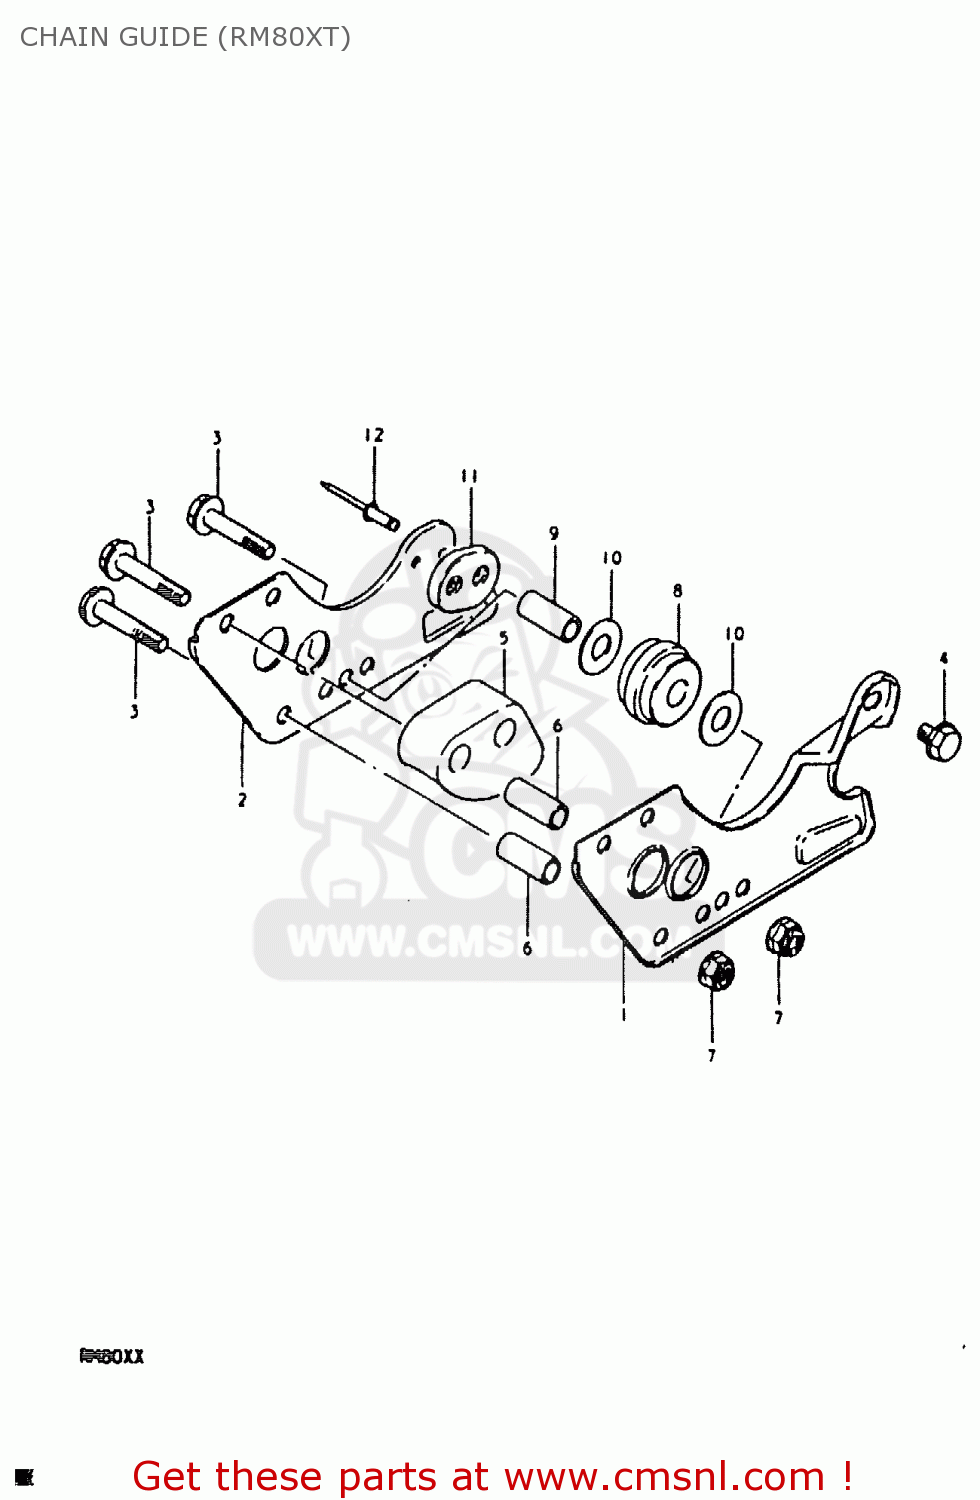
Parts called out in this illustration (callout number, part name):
1	GUIDE,CHAIN
2	PLATE,GUIDE CHAIN
3	BOLT 6X35
4	BOLT
5	ROLLER,CHAIN GUIDE
6	SPACER(6.8X10X24.2)
7	NUT
8	ROLLER,CHAIN GUIDE
9	SPACER,CHAIN GUIDE ROLLER
10	WASHER
11	PAD,DRIVE CHAIN GUIDE
12	RIVET
